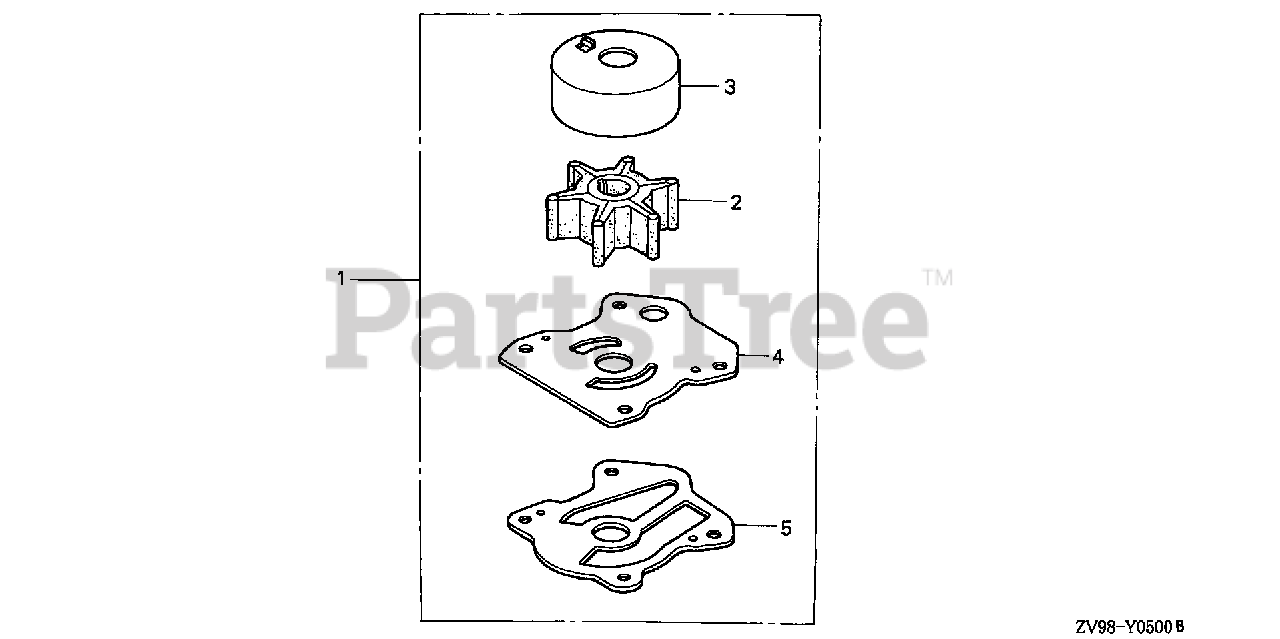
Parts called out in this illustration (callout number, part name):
1	PUMP KIT, IMPELLER
2	IMPELLER, PUMP
3	LINER, PUMP
4	COVER, IMPELLER
5	GASKET B, IMPELLER
